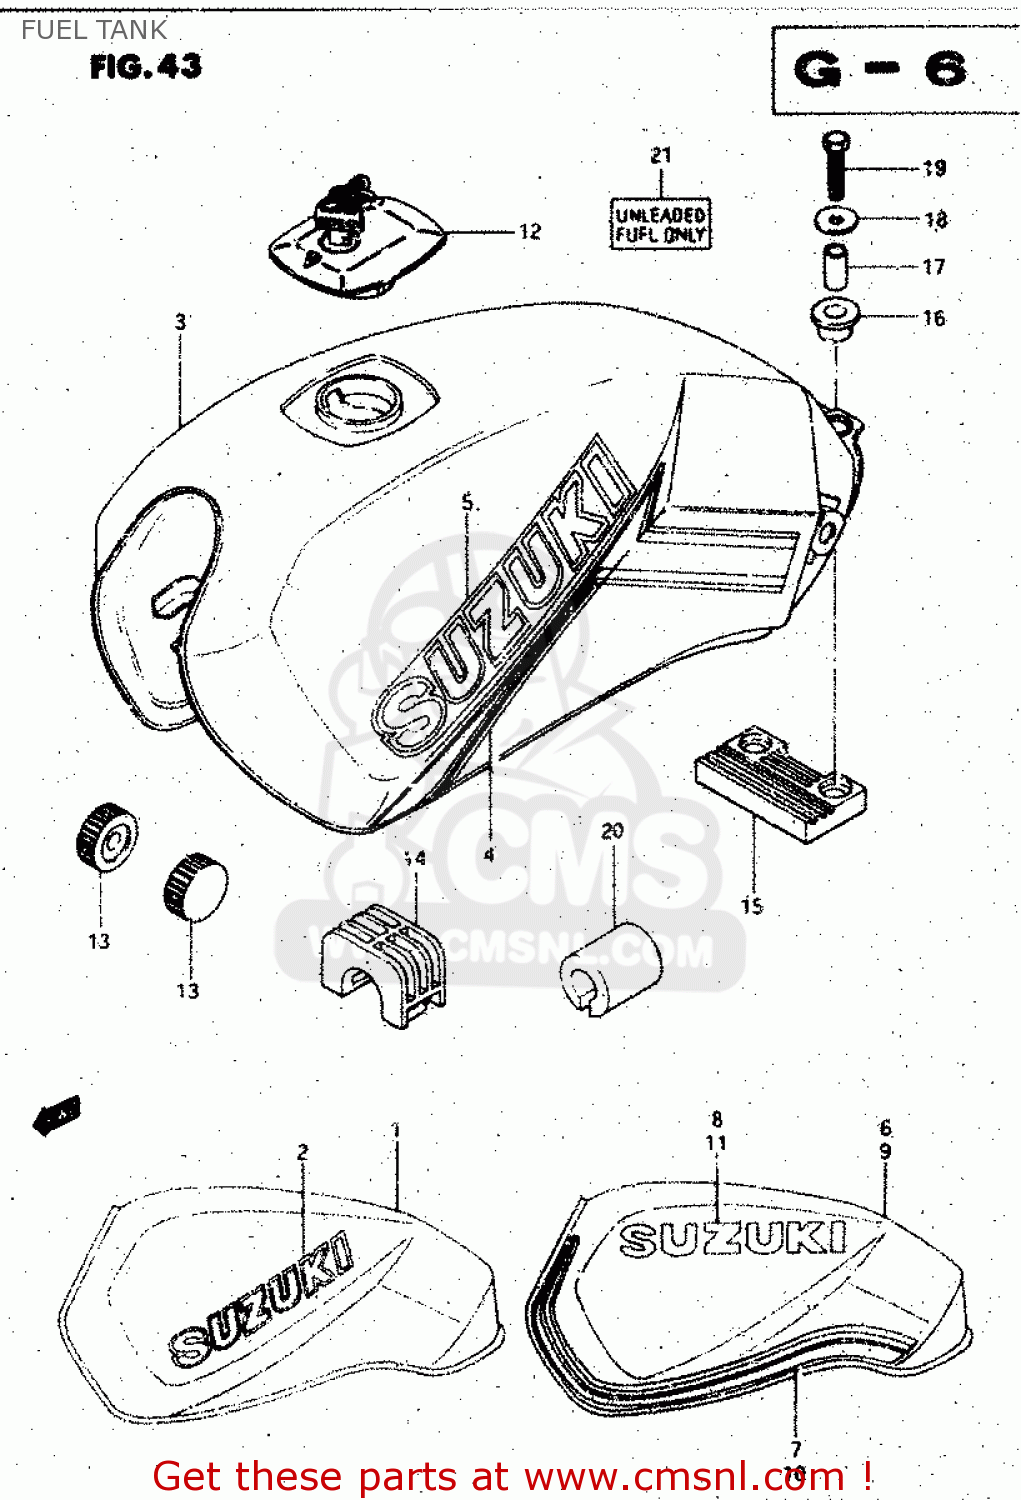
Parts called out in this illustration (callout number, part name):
1	TANK ASSY, FUEL (RED)
2	EMBLEM,FUEL TANK(WHITE)
3	TANK ASSY, FUEL (RED)
4	TAPE SET, FUEL TANK
5	EMBLEM (GOLD)
6	TANK ASSY, FUEL (WHITE)
7	TAPE SET, FUEL TANK
8	EMBLEM
9	TANK ASSY, FUEL (BLUE)
10	TAPE SET, FUEL TANK
11	EMBLEM
12	CAP SET,FUEL TANK
13	CUSHION
14	CUSHION,FUEL TANK UPR FR
15	CUSHION,TANK RR NO.1
16	CUSHION
17	SPACER(6.5X10.5X22.5)
18	WASHER
19	BOLT(6X35)
20	CUSHION
21	LABEL,FUEL CAUTION
